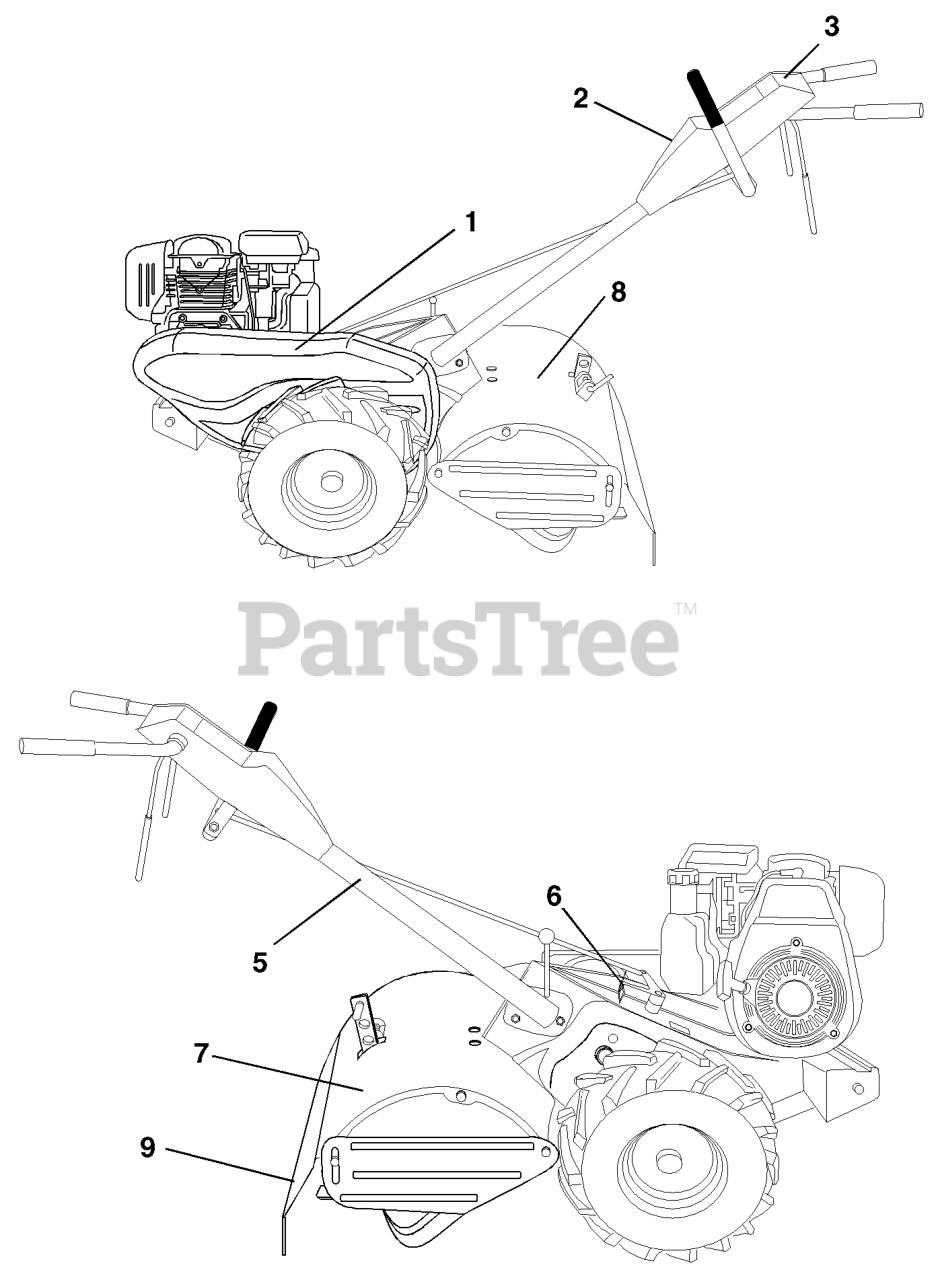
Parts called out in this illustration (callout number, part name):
2	DECAL, LOGO
3	DECAL, CONTROL PNL
5	DECAL TI (2 2)
6	DECAL.SHIFT.INDICATOR.TILLER
7	DECAL -CAUTION
8	DECAL, TINESHEILD
9	DECAL TI
